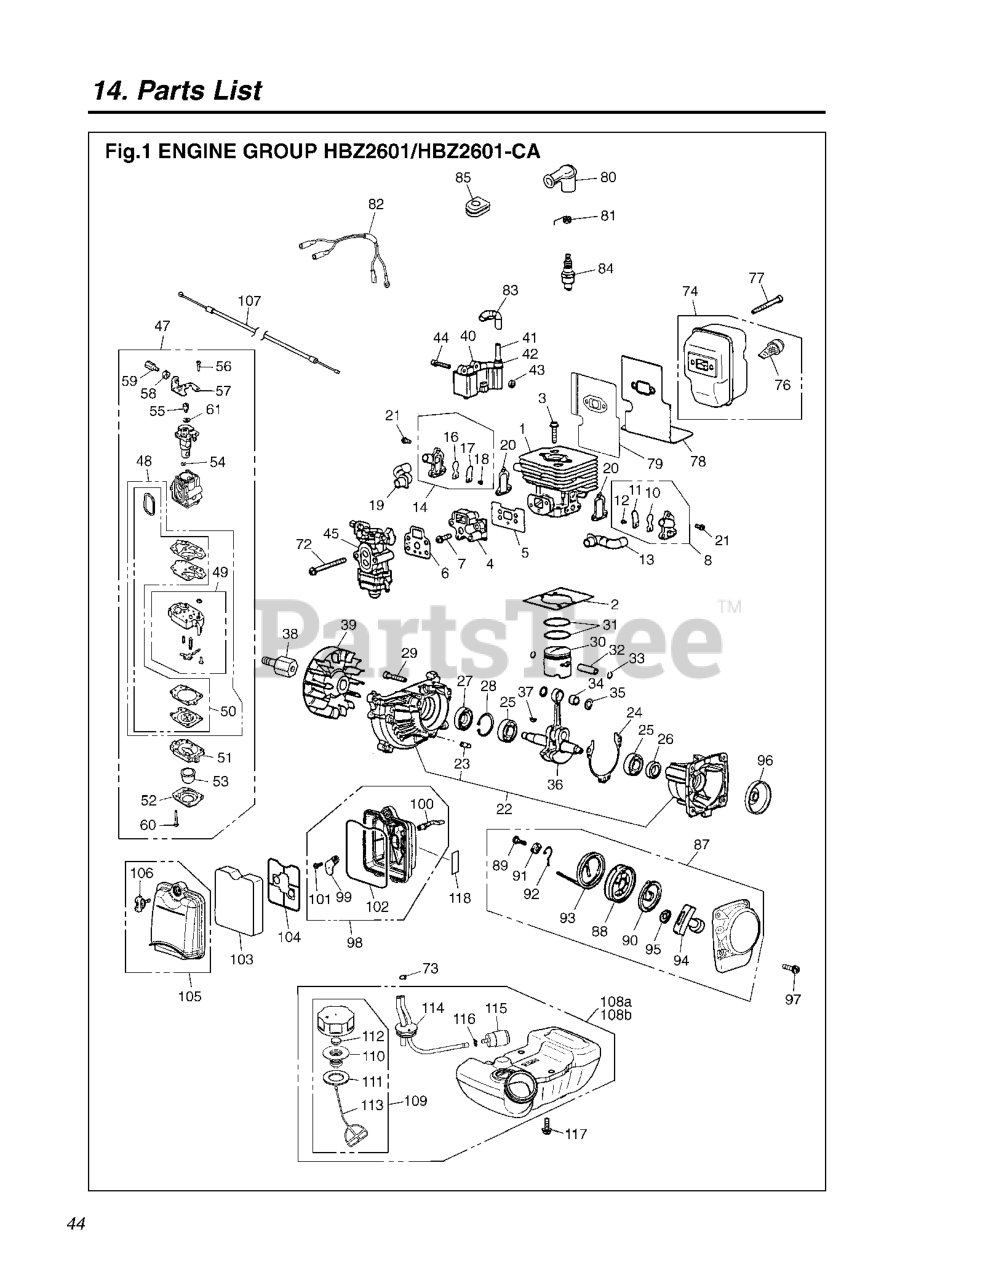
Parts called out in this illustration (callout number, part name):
1	CYLINDER
2	GASKET, BASE
3	BOLT
4	INSULATOR
5	GASKET.INSU
8	AIR CHECKER (S) ASSY
10	REEDVALVE
13	PIPE AIR (S)
14	AIR CHECKER (F) ASSY
16	REEDVALVE
19	PIPE AIR (F)
20	GASKET, VALVE
21	BOLT
22	CRANKCASE-C
23	PIN
24	GASKET.CASE
27	SEAL
32	PIN (RPLS T151341310)
34	BEARING (R550041410&114041330)
36	CRANKSHAFT COMP(RPLS481042000)
37	KEY
38	EXTENSION.
41	CORD (BLACK)
42	CAP
43	SPACER
47	CARBURETOR
48	REBUILD KIT
49	CARBURETOR BODY
50	GASKET KIT
52	1OVER
54	RING
55	SWIVEL
56	SCREW
57	BRACKET
58	NUT
59	ADJUSTER
61	WASHER
73	CLIP
74	MUFFLER-A
76	ARRESTER
78	GASKET, MUFFLER
79	PLATE, MUFFLER
84	PLUG CMR7H
85	GROMMET
87	RECOIL-A
90	SPRING, SPIRAL
91	COLLAR
92	SWING ARM
95	PLATE.STOPPER
98	BODY A
99	PLATE.CHOKE
100	LEVER CHOKE
101	SCREW
102	PACKING
103	ELEMENT
105	COVER A (RPLS T151382200)
108A	%TANK ASSY
110	HOLDER-A
114	PIPE-C
115	FILTER ASSY
116	CLIP
